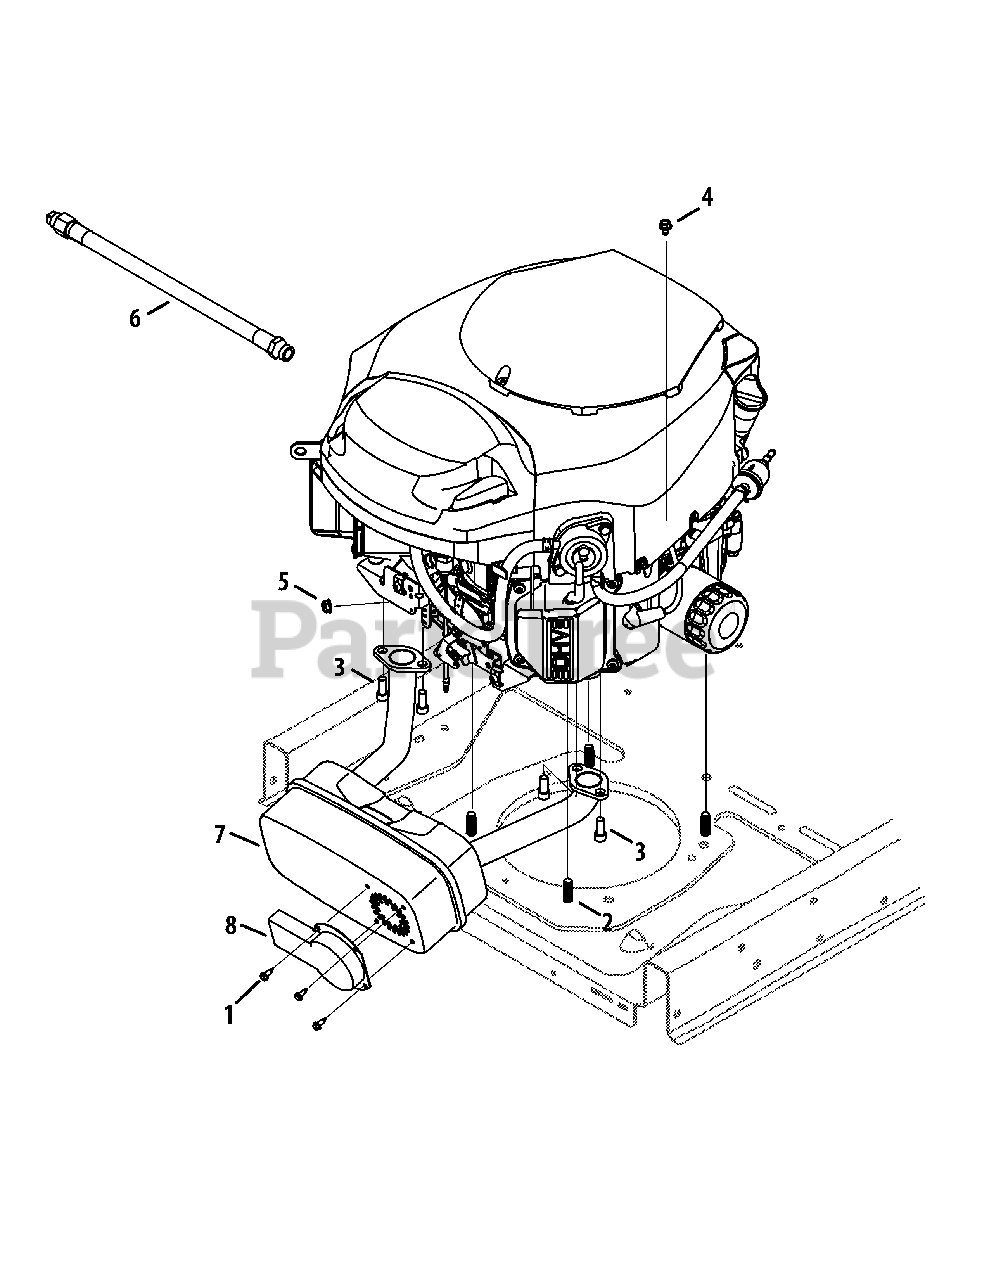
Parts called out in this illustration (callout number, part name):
1	Hex Washer Screw, #8-18 x .500
2	Hex Washer Screw, 3/8-16 x 1.00
3	Socket Head Screw, 5/16-18 x .750
4	Hex Washer Screw, 1/4-20 x .625
5	Flange Lock Nut, 1/4-20
6	Oil Drain Hose
7	Twin Muffler
8	Deflector, Muffler, Long
